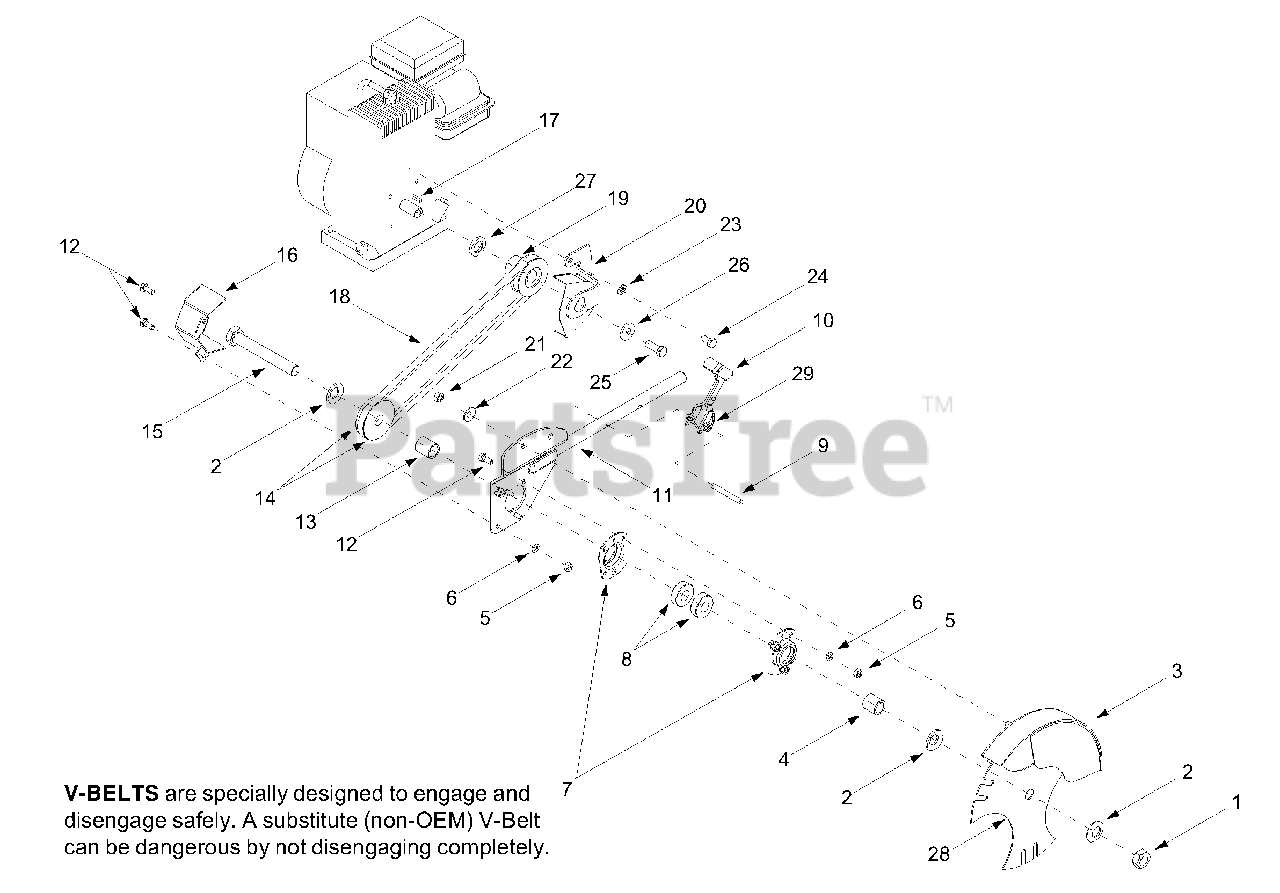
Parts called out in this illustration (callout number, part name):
1	Hex Jam Nut, 5/8-18
2	Bell Washer, .64 x 1.25 x .18
5	Hex Nut, 1/4-20
6	Lock Washer, 1/4
7	Bearing Housing
8	Ball Bearing, .62 x 1.38 x .44
9	Spirol Pin, 1/4 x 2.0
10	Adjustment Lever Assembly
13	Spacer, .635 x .88 x 1.03
14	Sheave, .6255 x .6295
15	Hex Cap Screw, 5/8-18 x 4.5
17	Square Key, 3/16 x .75
18	V-belt, 3/8
19	Engine Pulley, 3/8 x .75 x 2.38
22	Belleville Washer, .340 x .872
23	Lock Washer, 5/16
24	Hex Cap Screw, 5/16-24 x .625
25	Hex Cap Screw, 3/8-24 x 1.0
26	Flat Washer, .385 x 1.0 x .135
27	Spacer, .753 x 1.25 x .175
29	Double-torsion Spring
